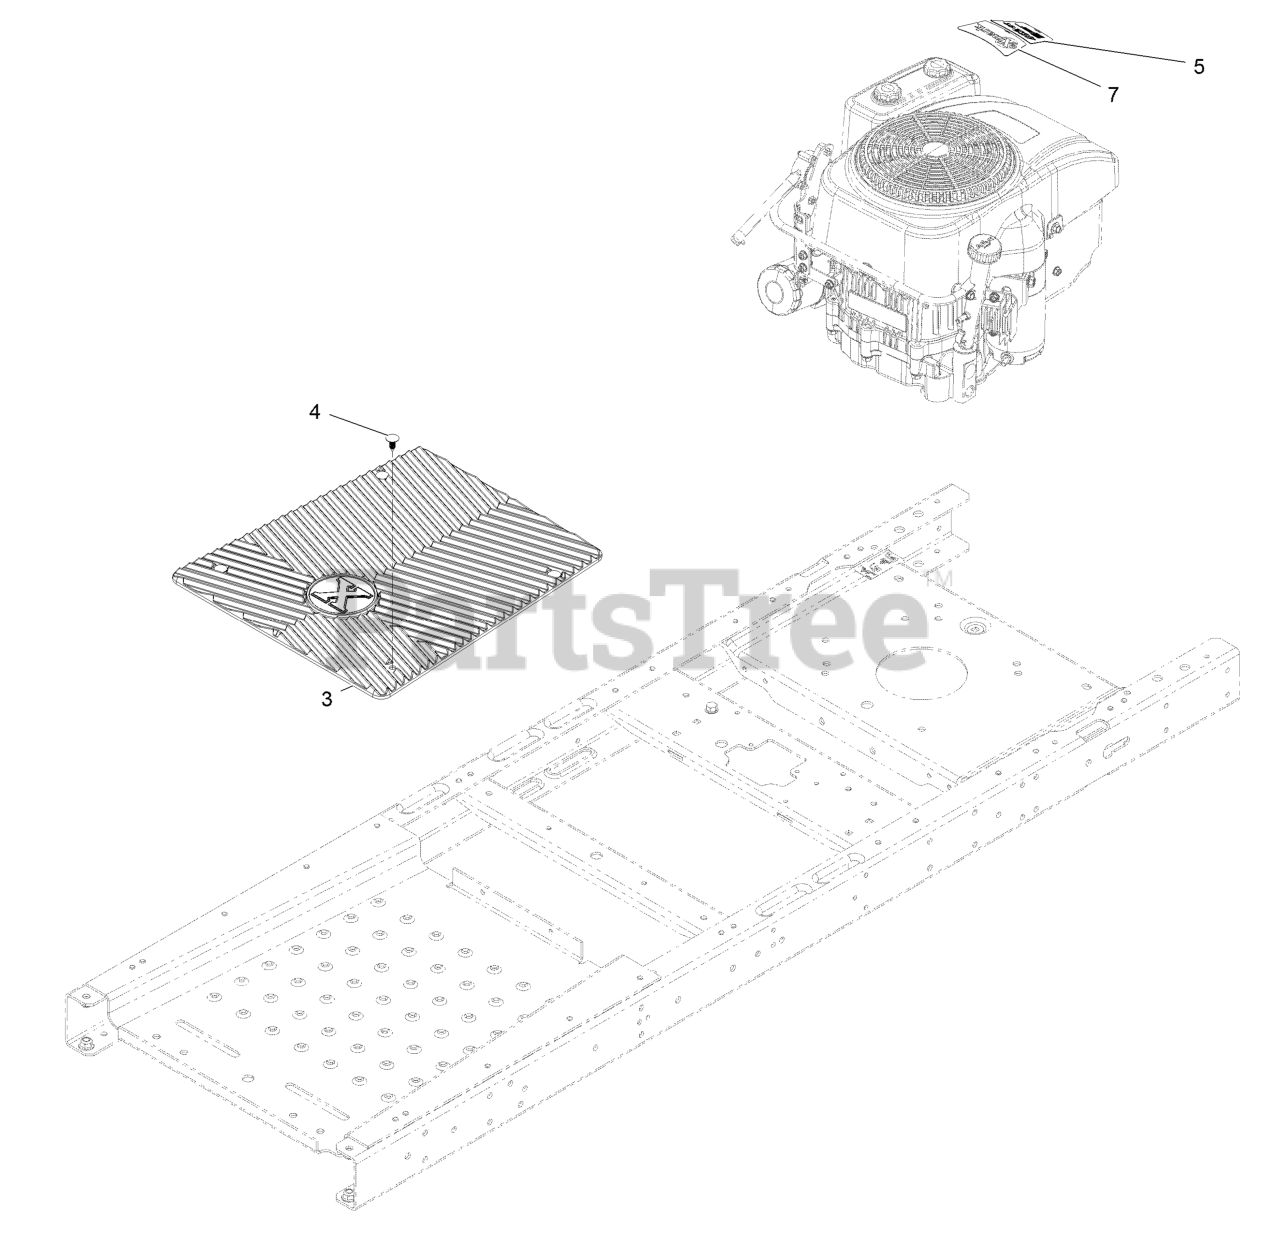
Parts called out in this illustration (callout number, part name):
3	FLOOR MAT- EXMARK
4	PLUG-PLASTIC
5	DECAL-ENGINE DISPLACEMENT
7	DECAL-ENGINE
